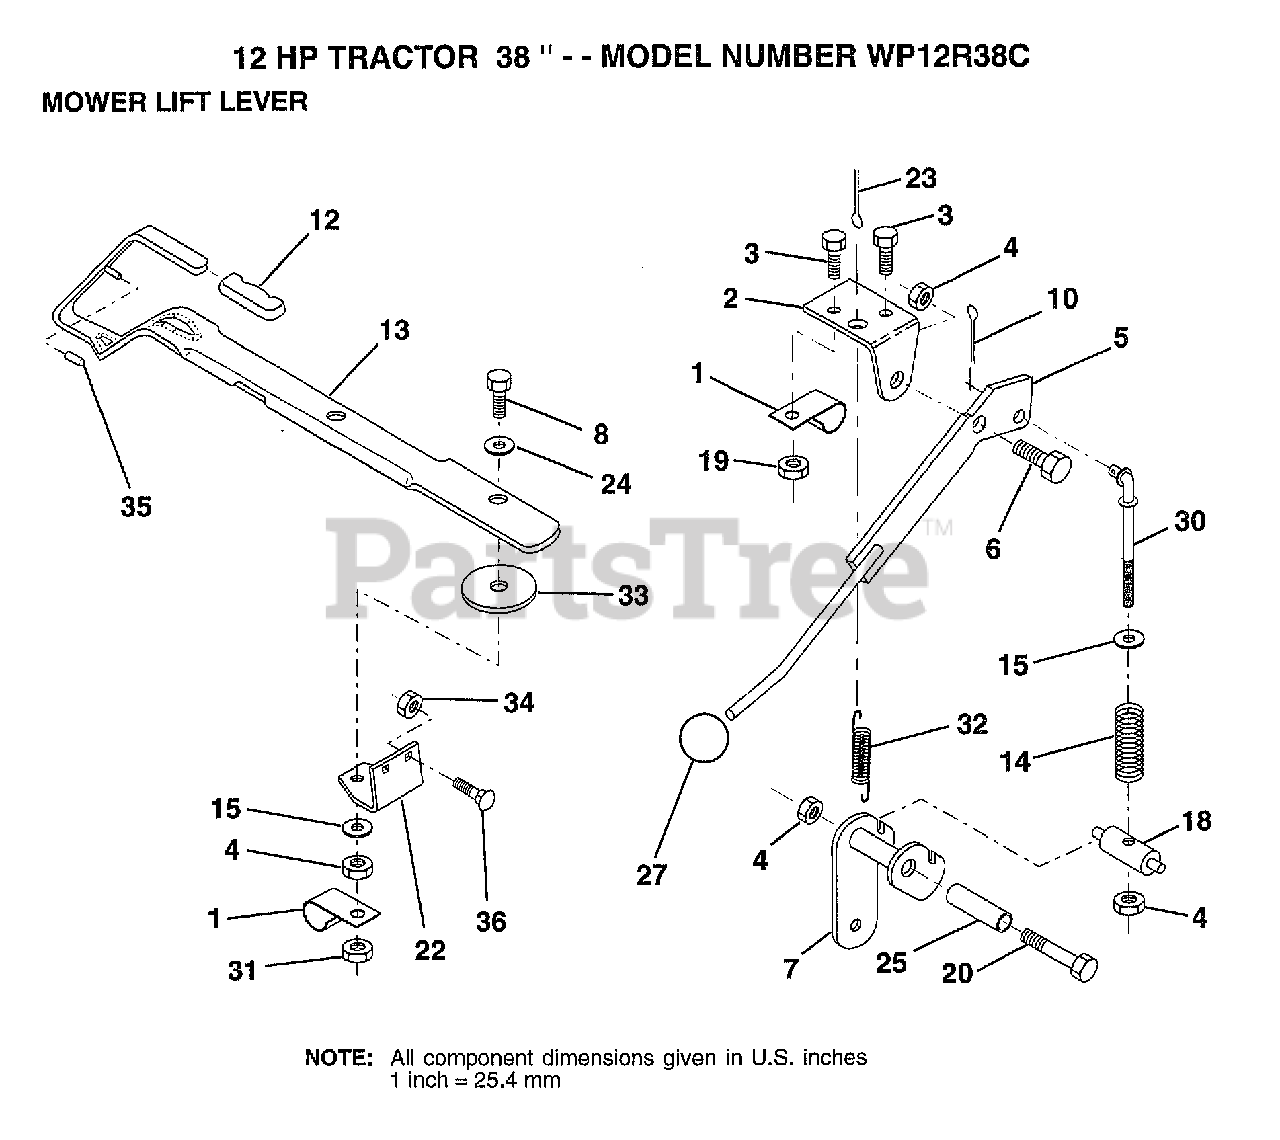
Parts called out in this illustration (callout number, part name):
1	"CLIP,INSULATOR"
2	BRKT CLUTCH
3	BOLT
4	NUT
5	CLUTCH LEVER AS
6	"BOLT, SHOULDER LT"
7	ARM.CLUTCH.ASM
8	BOLT
10	COTTER PIN
12	GRIP HANDLE
13	LEVER LIFT LR
14	COMP CLUTCH SPRNG
15	WASHER HYT
18	TRUNNION
20	BOLT
22	LIFT LEVER BRKT
24	WASHER
25	TUBE SPACER
27	KNOB
30	ROD TENSION CLUTC
31	LOCKNUT
32	SPRING EXT
33	WASHER
34	NUT
35	VINYL CAP RED
36	BOLT
